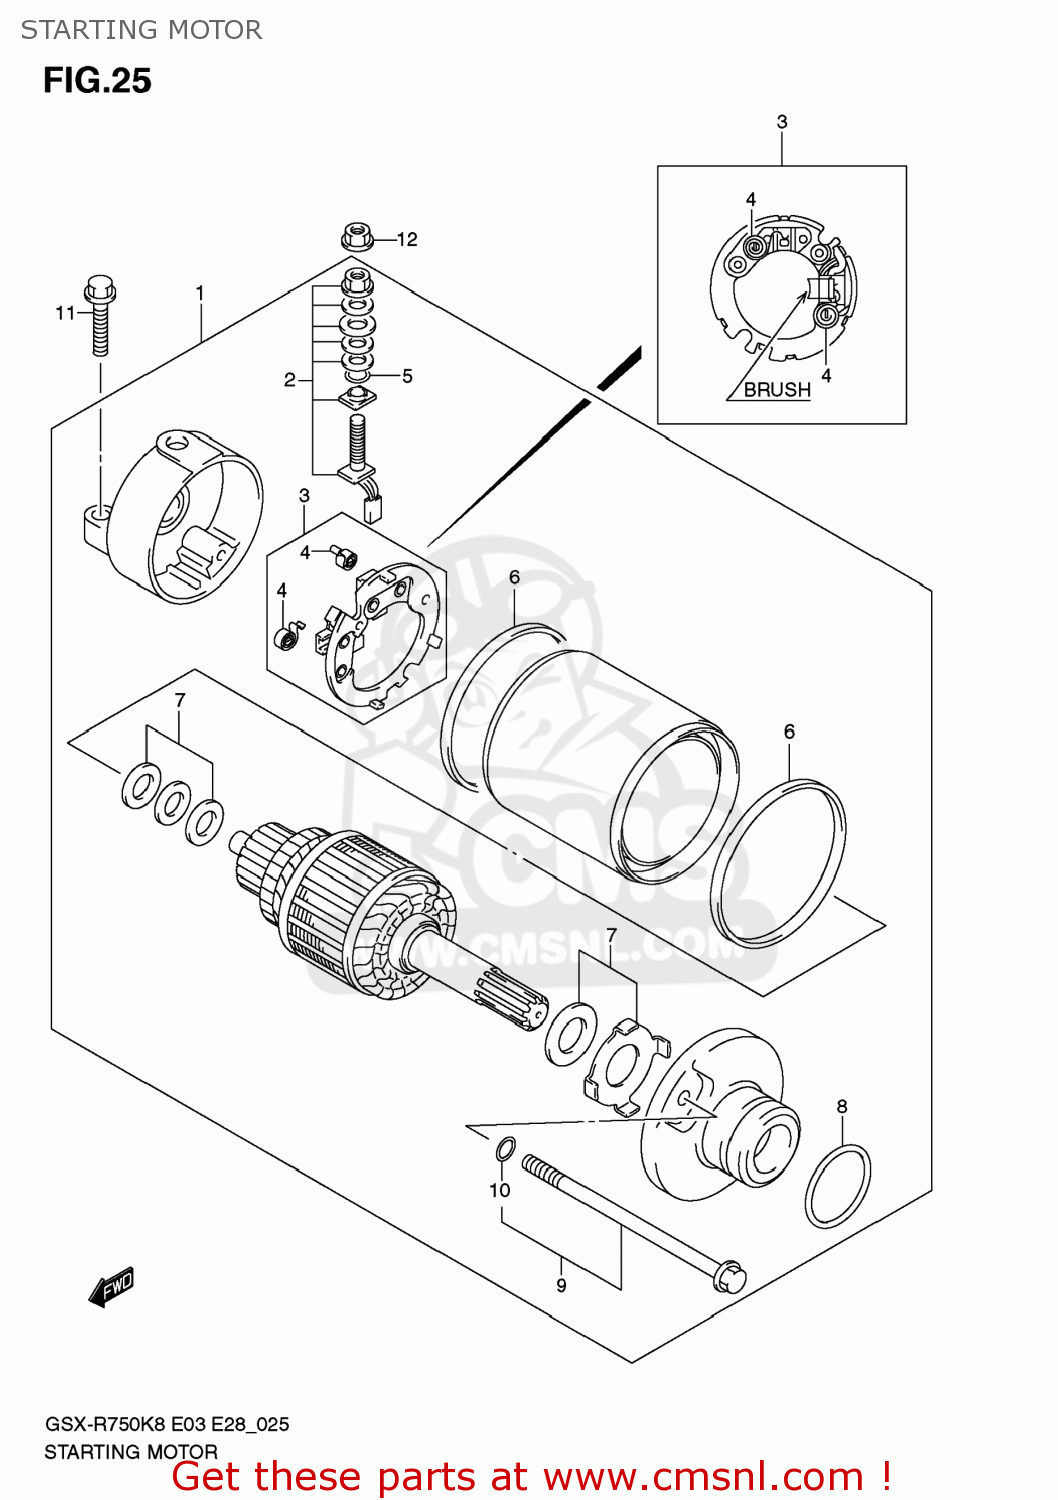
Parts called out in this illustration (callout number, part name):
1	MOTOR ASSY,STARTING
2	BRUSH TERMINAL SET
3	BRUSH HOLDER SET
4	SPRING,BRUSH
5	O RING
6	O RING
7	SHIM SET,STARTING MOTOR
8	O RING(D:3,ID:24.5)
9	SET,BOLT ASSY
10	O RING
11	BOLT(6X25)
12	NUT
